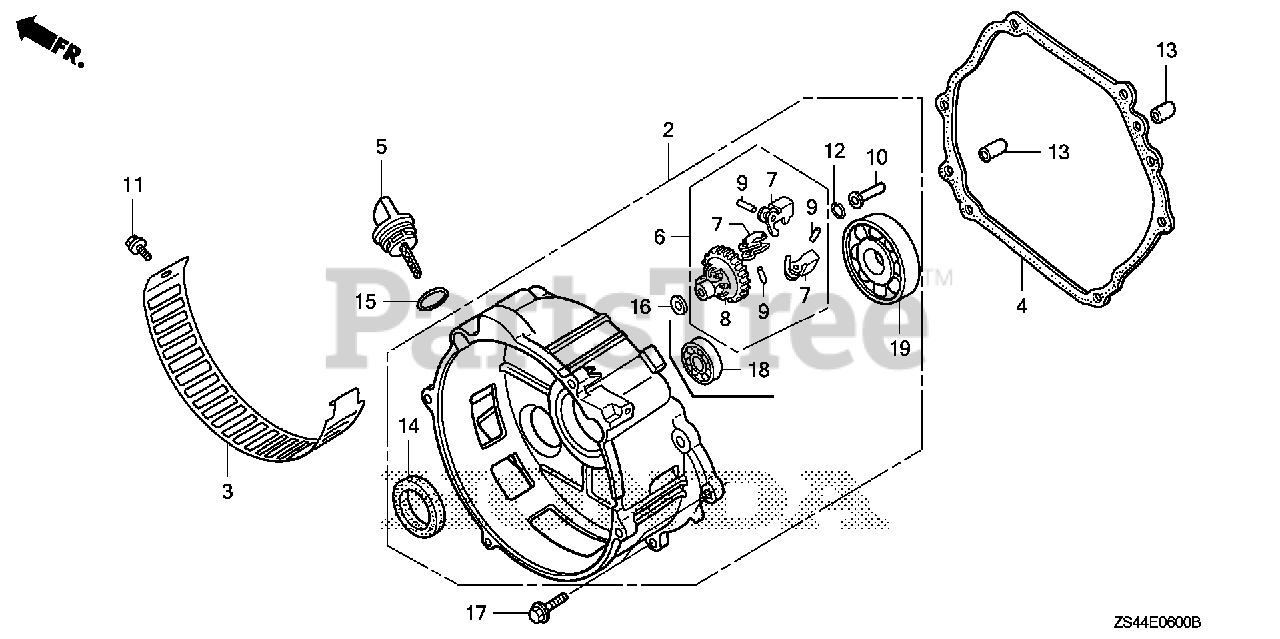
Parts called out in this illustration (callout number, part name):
2	COVER ASSY., CRANKCASE
3	COVER, DUCT
4	GASKET, CASE COVER
5	CAP, OIL FILLER
6	GOVERNOR ASSY.
7	WEIGHT, GOVERNOR
8	HOLDER, GOVERNOR WEIGHT
9	PIN, GOVERNOR WEIGHT
10	SLIDER, GOVERNOR
11	BOLT, FLANGE (5X10)
12	CLIP, GOVERNOR HOLDER
13	PIN, DOWEL (8X12)
14	OIL SEAL (30X46X8)
15	O-RING (26X2.7)
16	WASHER, PLAIN (6MM)
17	BOLT, FLANGE (8X35)
19	BEARING, RADIAL BALL (6206)
